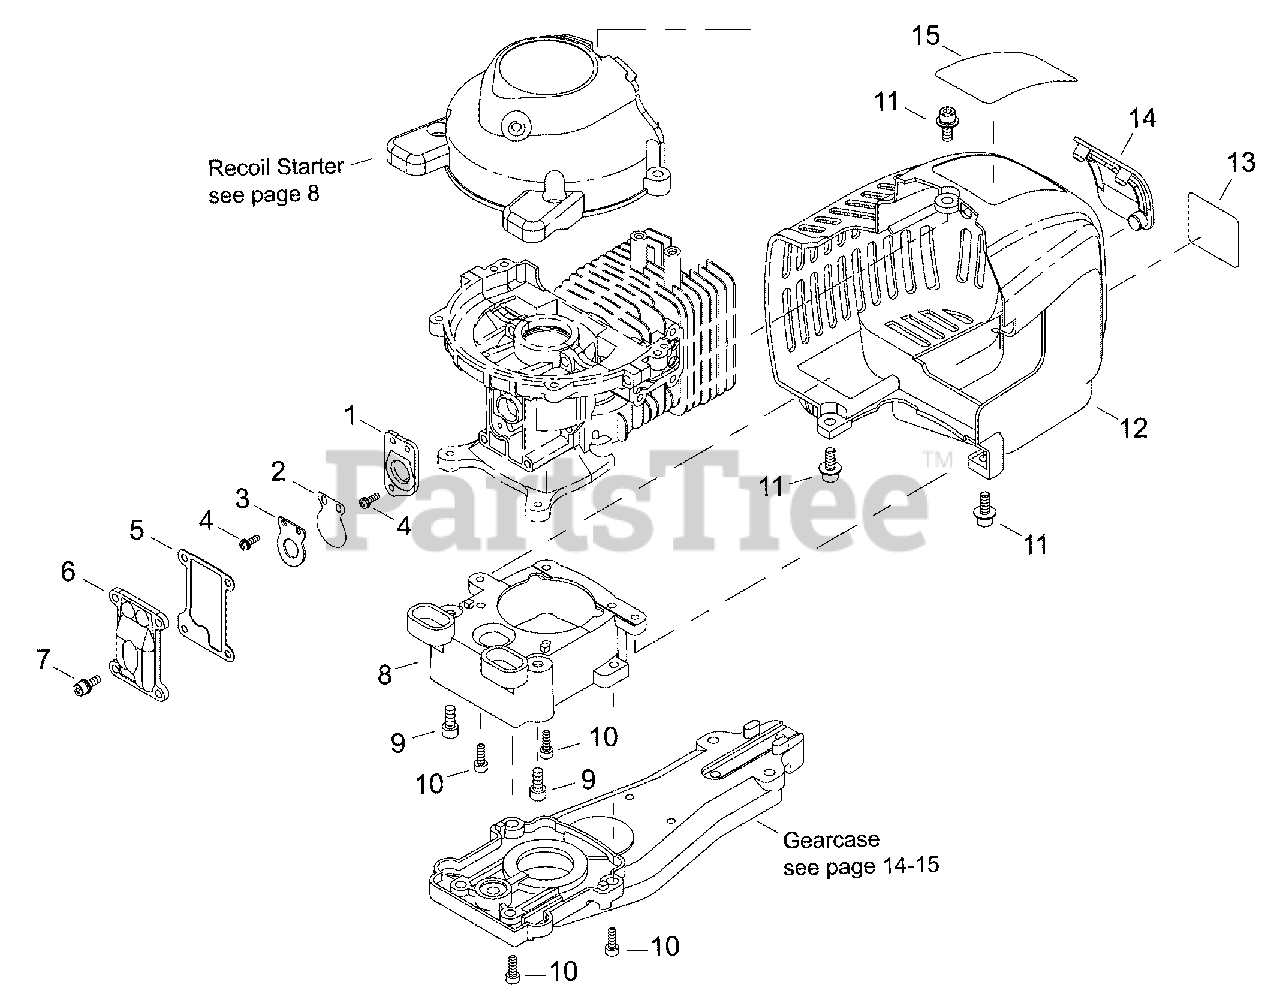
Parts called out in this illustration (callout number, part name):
1	PLATE, REED BACKING
2	VALVE, REED
3	STOP, REED VALVE
4	SCREW M3×10
5	GASKET, REED VALVE
6	COVER, REED VALVE
7	BOLT M4×12
8	ADAPTOR, GEAR CASE
9	BOLT 5×12
10	BOLT 4×12
11	BOLT, ADHESIVE M5×14
12	COVER, ENGINE
13	LABEL, E4 HT3000
14	COVER, SPARK PLUG
15	LABEL, SWISHER E4
